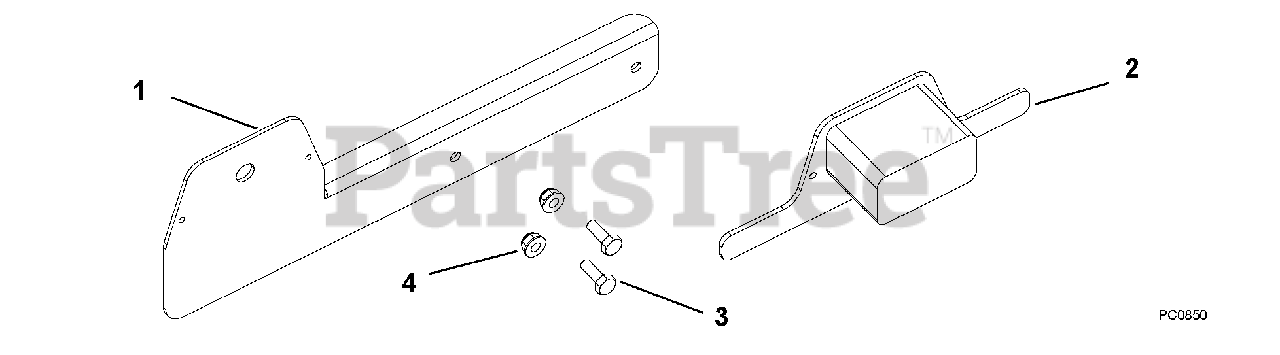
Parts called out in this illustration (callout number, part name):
1	Bracket, License Plate (Ships preassembled with item 2)
2	Light (Ships preassembled with item 1)
3	Bolt, Hex .25-20 x .75
4	Nut, Nyloc Flange .25-20
